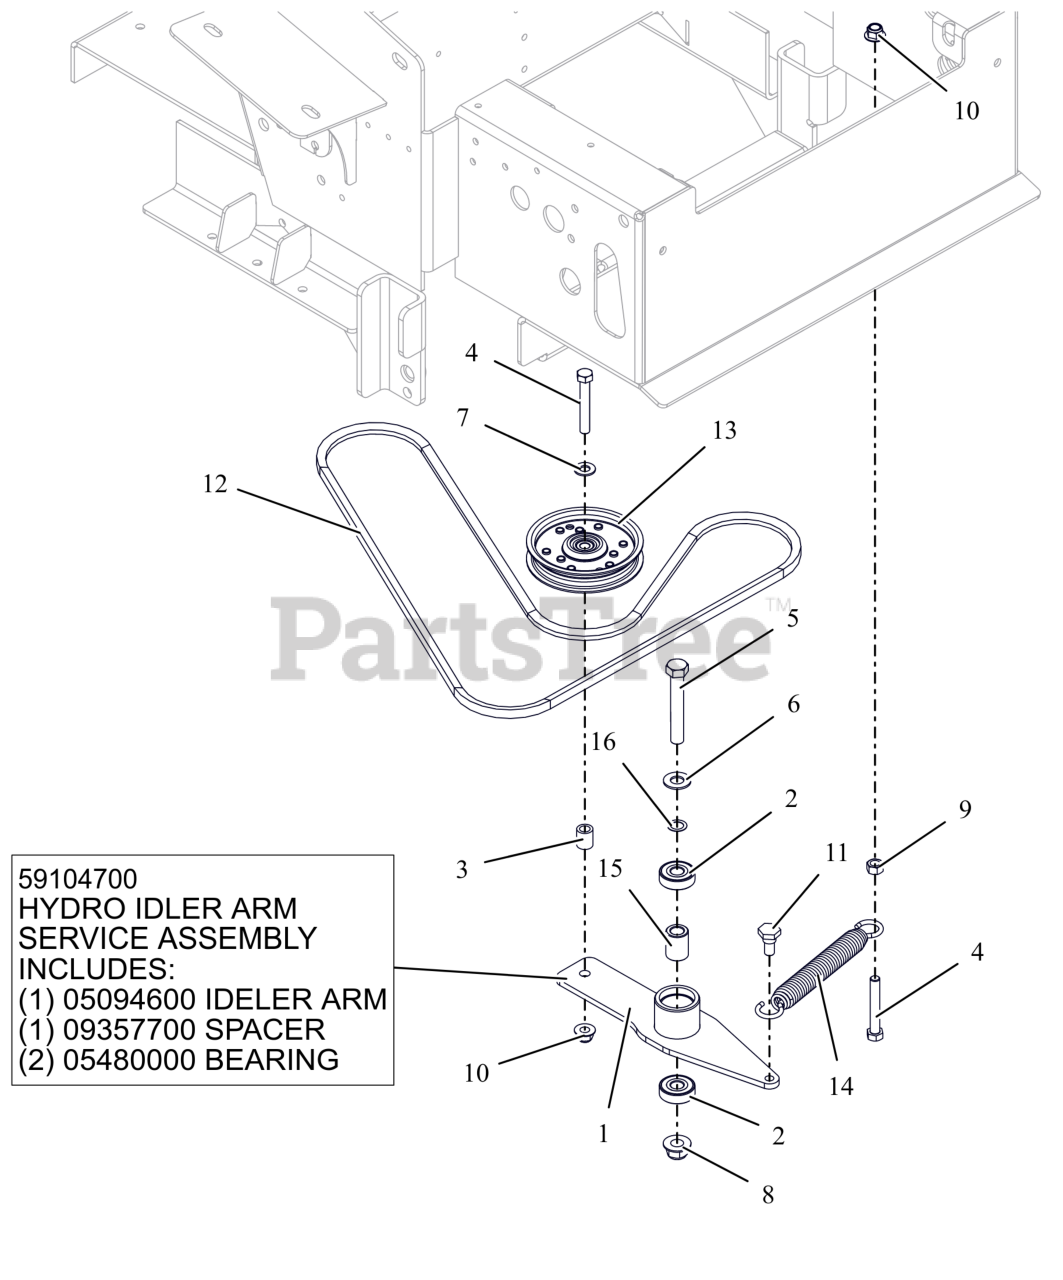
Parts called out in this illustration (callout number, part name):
1	HYDRO IDLER ARM ASSEMBLY
1	WMT- HYDRO DRIVE IDLER ARM
1	SPACER .510 X .867 X 1.1485
1	BRG-BALL .50X1.38X.438 SEALED
2	BRG-BALL .500X1.38X.437
3	BSHG-SLV .407X.625X.750 PL
4	BLT, HEX .38-16X2.50 G5 ZCC
5	BLT,HEX .50-13X3.25 G5 ZCC
6	WSHR, FLT .557X1.040X.102 ZCC
7	WSHR,FLT .406X.812X.065 ZCC
8	NUT,NYL-FLG .50-13 GF ZCC
9	NUT-STD .375-16 G2 ZCC
10	NUT,NYL-FLG .38-16 GF ZCC
11	BLT,SHLDR EP .38-16X.30 HEX YZ
12	V-BELT, A-COGGED
13	ASM, 4" IDLER (.75 WIDE)
14	SPRING- EXTENSION
15	SPACER .510 X .867 X 1.1485
16	WASHER, .500X.750X.020 THRUST
